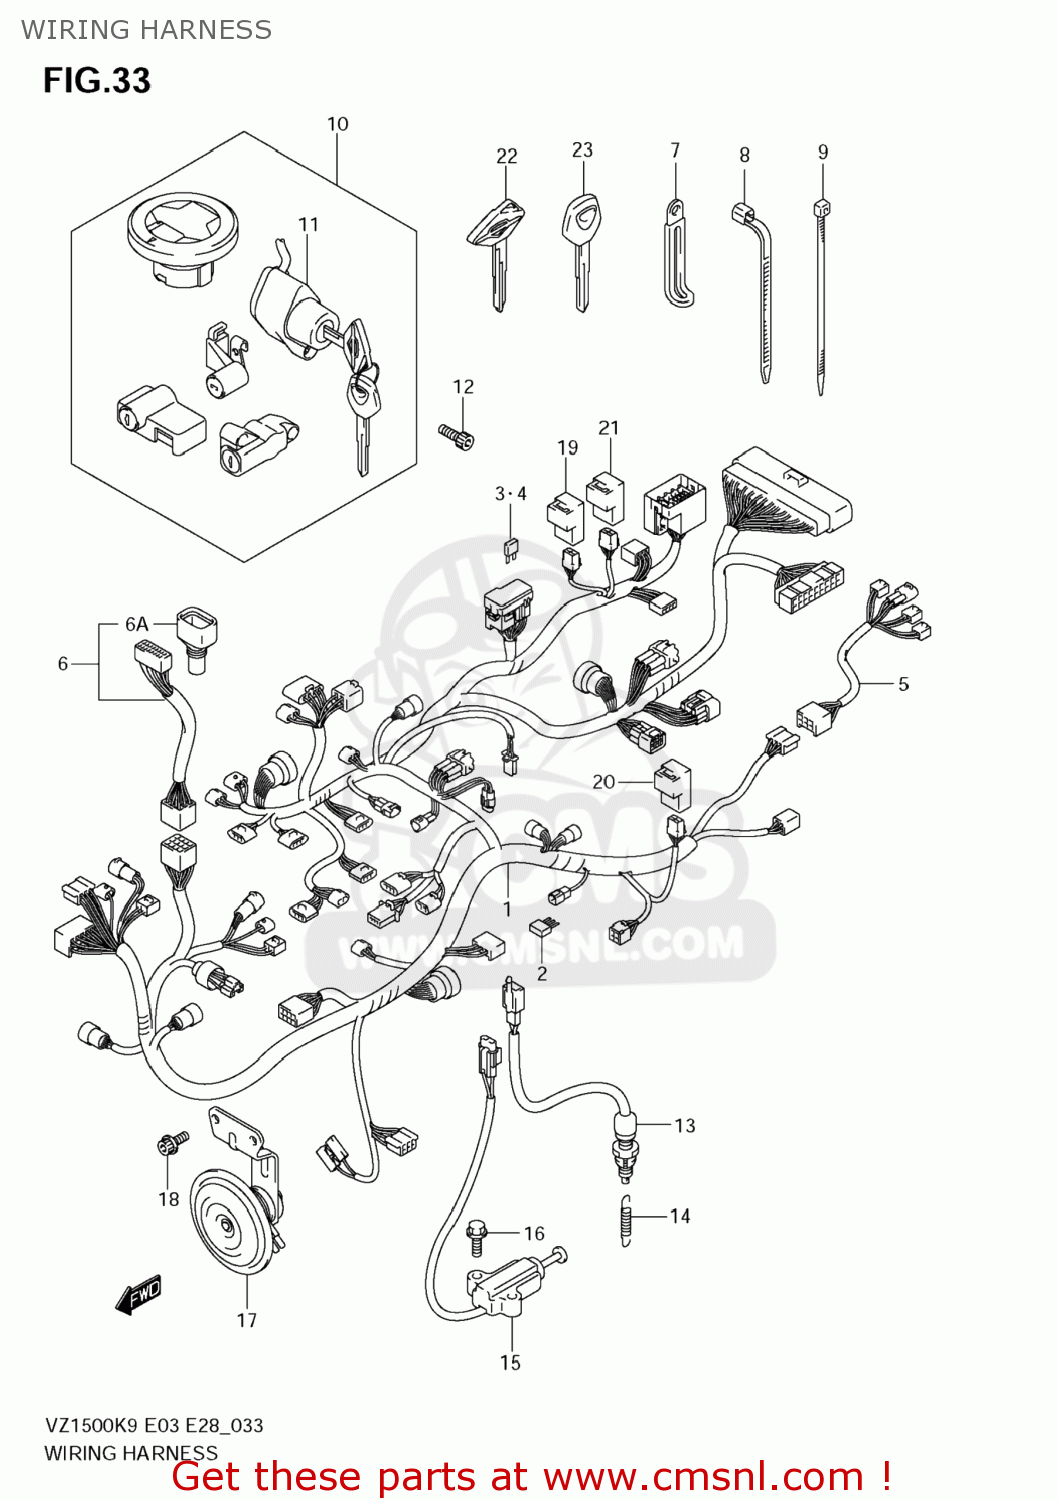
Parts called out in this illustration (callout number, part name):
1	HARNESS,WIRING
2	DIODE(STANLEY DE8804)
3	FUSE(10A)
4	FUSE(15A)
5	WIRE,RR COMB
6	WIRE,METER LEAD
6A	COVER,SPEEDOMETER COUPLER
7	CLAMP(L:45)
8	CLAMP(L:125)
9	CLAMP(L:145)
10	LOCK SET
11	SWITCH ASSY,IGNITION
12	BOLT
13	SWITCH ASSY,STOP LAMP
14	SPRING
15	SWITCH ASSY,SIDE STAND
16	BOLT
17	HORN ASSY
18	BOLT
19	RELAY ASSY
20	RELAY ASSY
21	RELAY ASSY
22	KEY,BLANK(BOULEVARD)
23	KEY,BLANK
